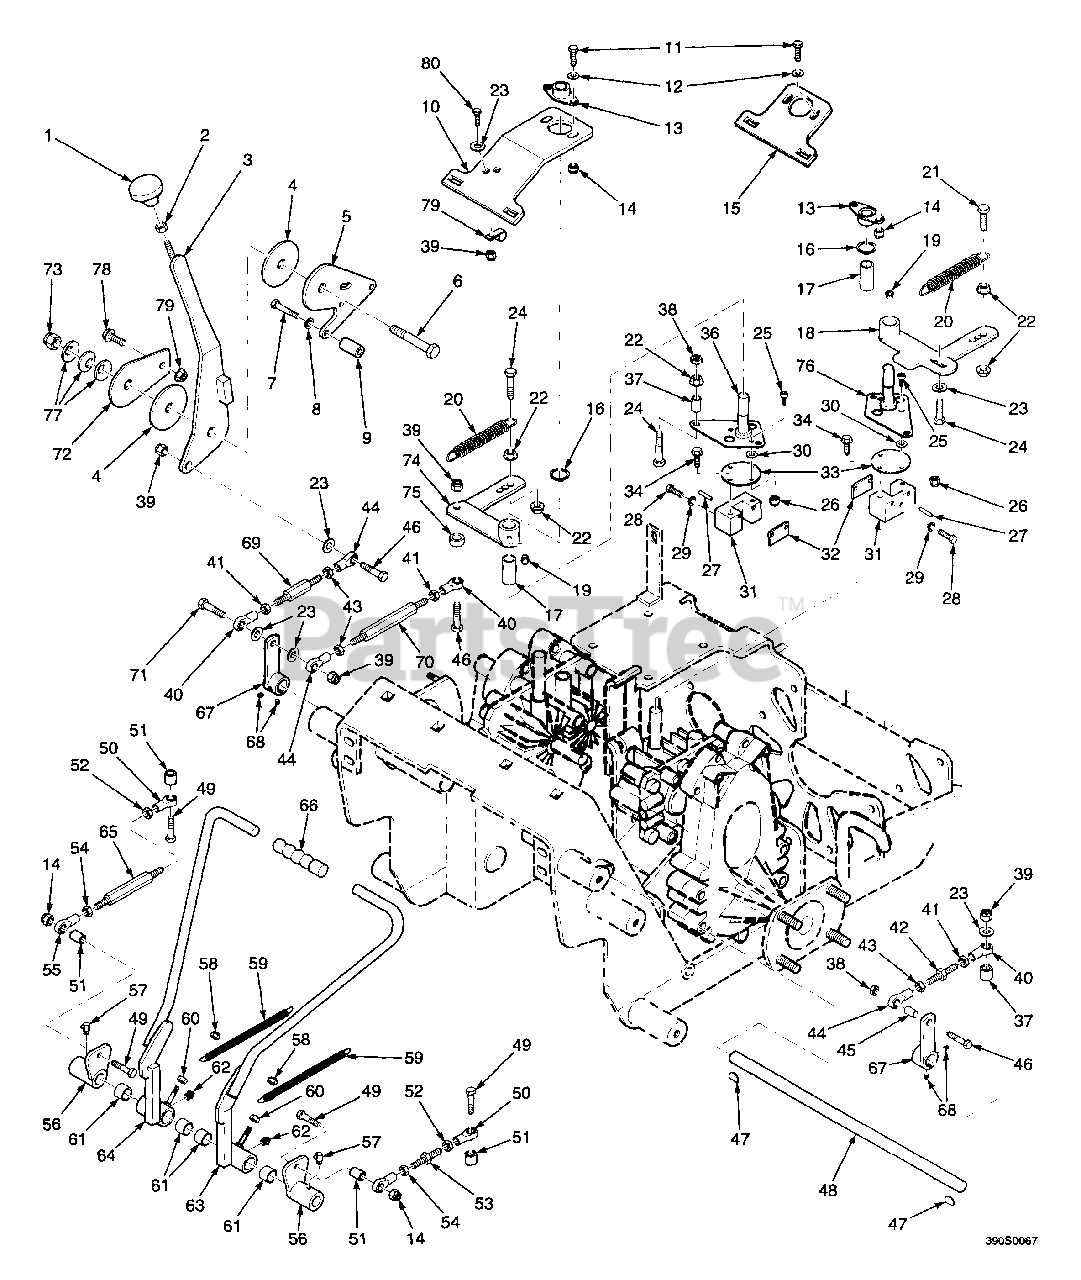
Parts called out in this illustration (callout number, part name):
2	Hex Nut, 3/8-16
3	Lever, Speed Control
4	Disc, Friction
5	Mounting, Plate, Speed Selector
6	Bolt, Hex Head, 5/8-11 x 2-1/4"
7	Bolt, Hex head, 5/16-18 x 2-1/2"
8	Lockwasher, 5/16"
9	Spacer, Speed Control
10	Mounting Plate, Speed Control
11	Bolt, Hex Head, 5/16-18 x 3/4"
12	Flatwasher, 5/16 (.375 x .875 x .083)
13	Bushing, Self-Aligning
14	Hex Locknut, Elastic Stop, 5/16-18
15	Mounting Plate, Left Bearing
16	Ring, Retaining, .625"
17	Bushing, Oilite, .627" ID
18	Lever, L.H. Speed Control
19	Grease Fitting
20	Spring
21	Bolt, Hex Head, 3/8-16 x 1-1/4"
22	Serr. Fl. Hex Nut, 3/8-16
23	Flatwasher, 3/8 (.391 x .938 x .105)
24	Bolt, Hex Head, 3/8-16 x 2.0"
25	Capscrew, Socket Head, 1/4-20 x 1/2"
26	Hex Locknut, Elastic Stop, 1/4-20
27	Roll Pin
28	Bolt, Hex Head, 1/4-20 x 1-1/4"
29	Lockwasher, 1/4"
30	Flatwasher, 1/4 (.281 x .625 x .065)
31	Block, Pump Control
32	Clamp Plate, Pump Control
33	Plate, Coupler
34	Serr. Fl. Hex Head CPSCRW, 1/4-20 x 3/4"
36	Arm, R.H. Pump Control
37	Stop, Pump Arm
38	Hex Locknut, 3/8-16
39	Hex Locknut, Elastic Stop, 3/8-16
40	Ball Joint, 3/8-24 R.H. Thread
41	Hex Nut, 3/8-24 R.H. Thread
42	Link
43	Hex Nut, 3/8-24 L.H. Thread
44	Rod End, 3/8-24 L.H. Thread
45	Sleeve
46	Bolt, Hex Head, 3/8-16 1-1/2"
47	Key, 3/16 x 5/8 Woodruff
48	Shaft Speed Control
49	Bolt, Hex Head, 5/16-18 x 1-1/2"
50	Rod End, 5/16-24 R.H. Thread
51	Spacer
52	Hex Nut, 5/16-24 R.H. Thread
53	Link, Adjustment
54	Hex Nut, 5/16-24 L.H. Thread
55	Rod End, 5/16-24 L.H. Thread
56	Control Lever
57	Grease Fitting, 90ø
58	Hex Locknut, Elastic Stop, 5/16-18
59	Spring, Handle Return
60	Hex Locknut, 5/16-18
61	Bushing, Oilite, .753 ID
62	Grease Fitting
63	Lever, L.H. Control
64	Lever, R.H. Control
65	Link, R.H. Adjustment
66	Grip, Hand Control
67	Lever, Speed Control
68	Setscrew, Socket Head, 1/4-20 x 1/4"
69	Link, Speed Control
70	Link
71	Bolt, Hex Head, 3/8-16 x 1-3/4"
72	Plate, Speed Selector
73	Hex Locknut, Elastic Stop 5/8-11
74	Lever, R.H. Speed Control
75	Spacer
76	Arm, L.H. Pump Control
77	Washer, Belleville, 5/8"
78	Grease Fitting
79	Clamp, .75 Dia.
80	Hex Head Bolt, 3/8-16 x 1.0"
